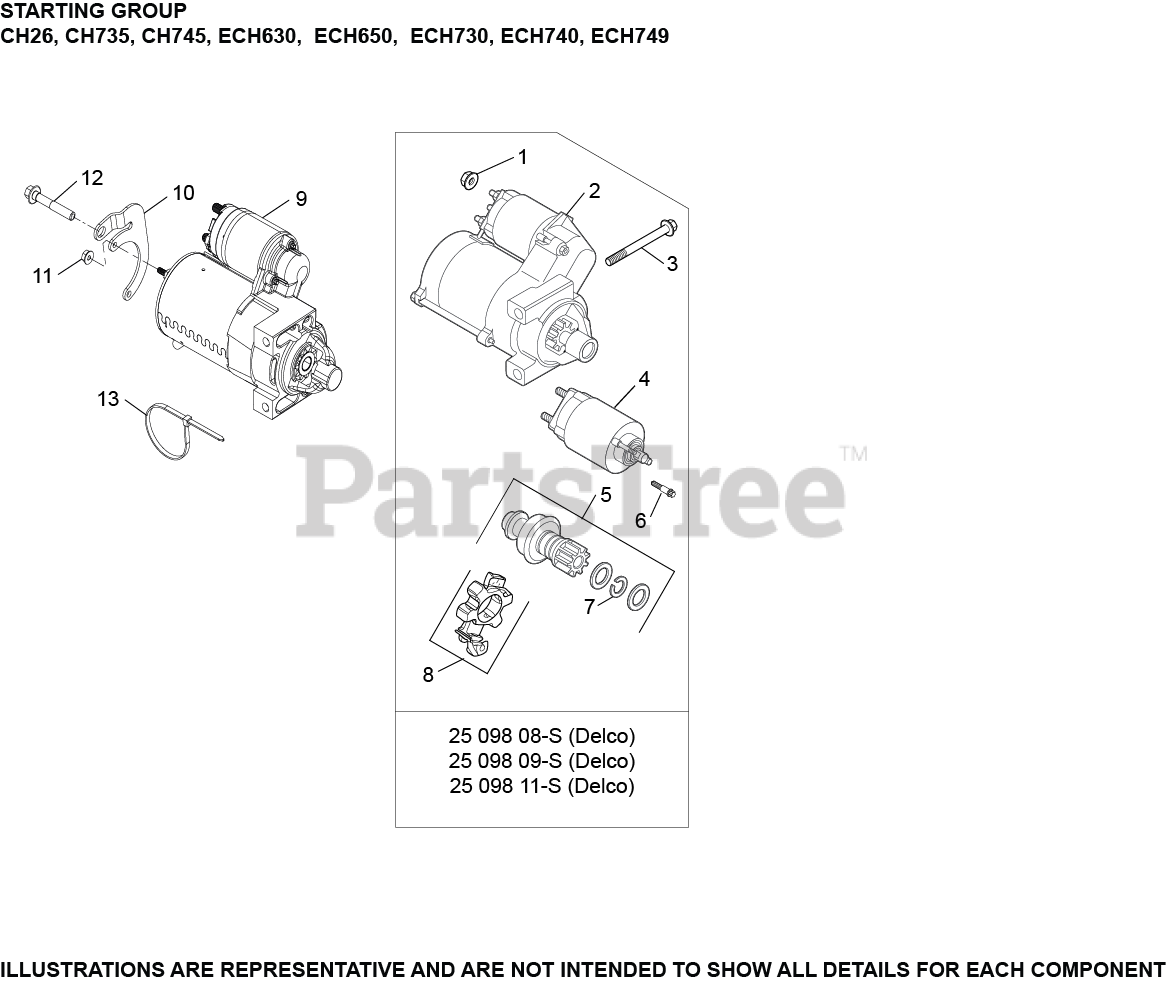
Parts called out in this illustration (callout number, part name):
1	NUT, FLG M8X1.25
2	ELECTRIC STARTER - SOLENOID SHIFT USE 25 098 20-s
3	SCREW, FLG M8X1.25X80
4	KIT, SOLENOID
5	KIT, STARTER PINION
6	SCREW, EXTERNAL TORX HEAD
7	RING, RETAINING
8	KIT, BRUSH HOLDER
